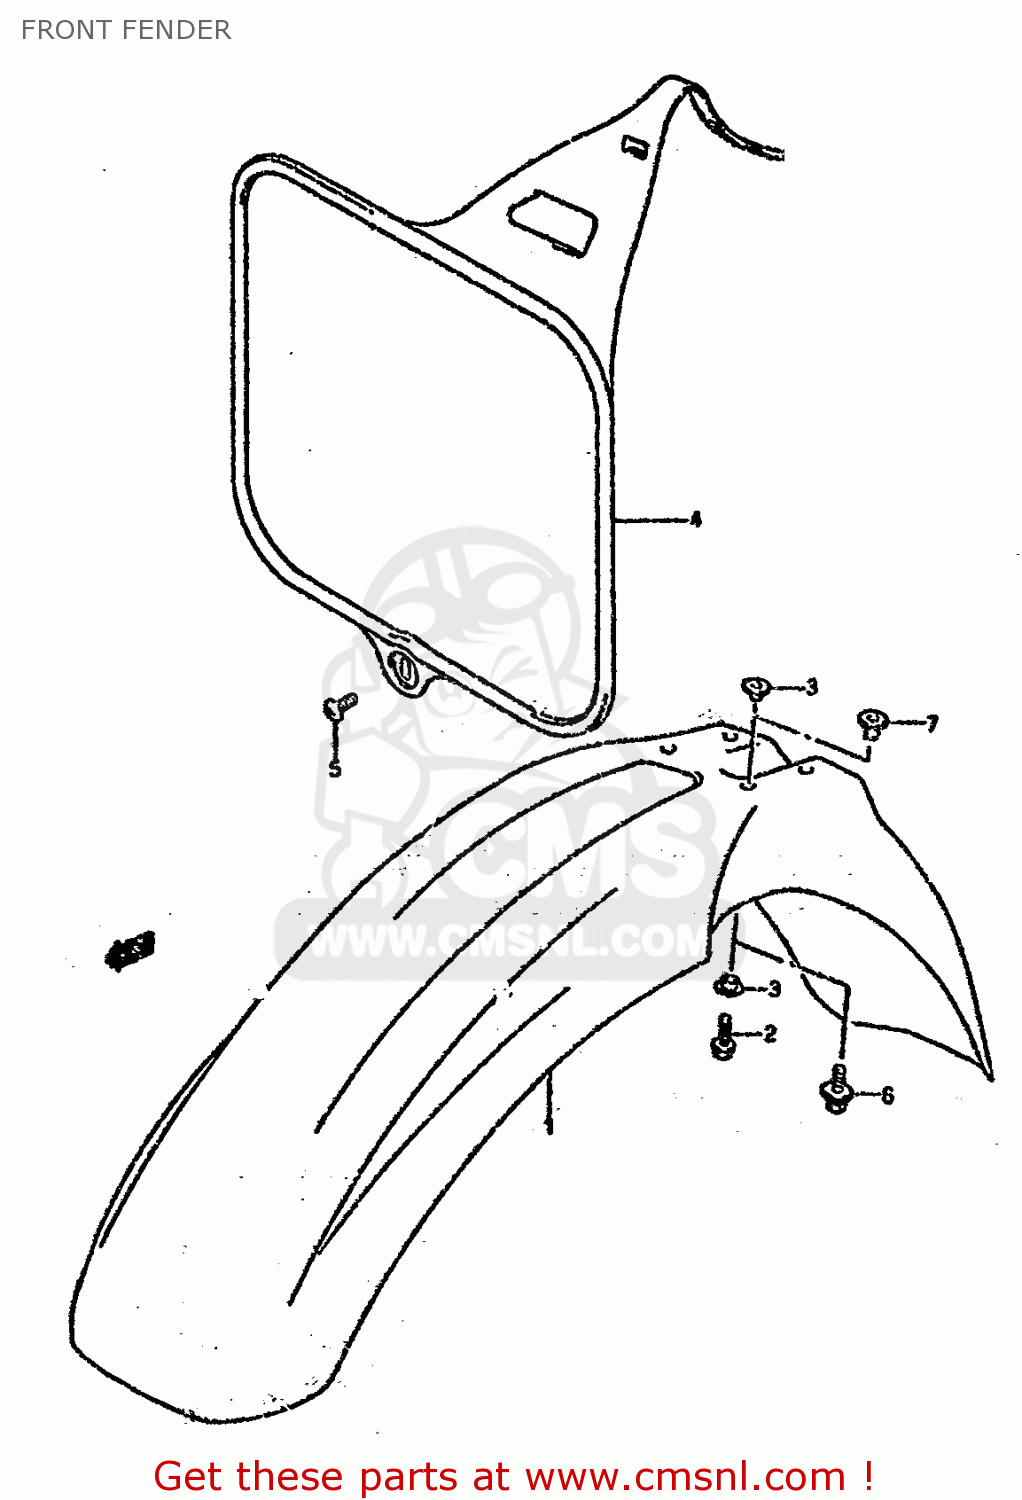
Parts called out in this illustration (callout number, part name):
1	FENDER,FRONT
2	BOLT
3	WASHER
4	PLATE,NUMBER FRONT(WHITE)
5	SCREW
6	BOLT(6X16)
7	WASHER
